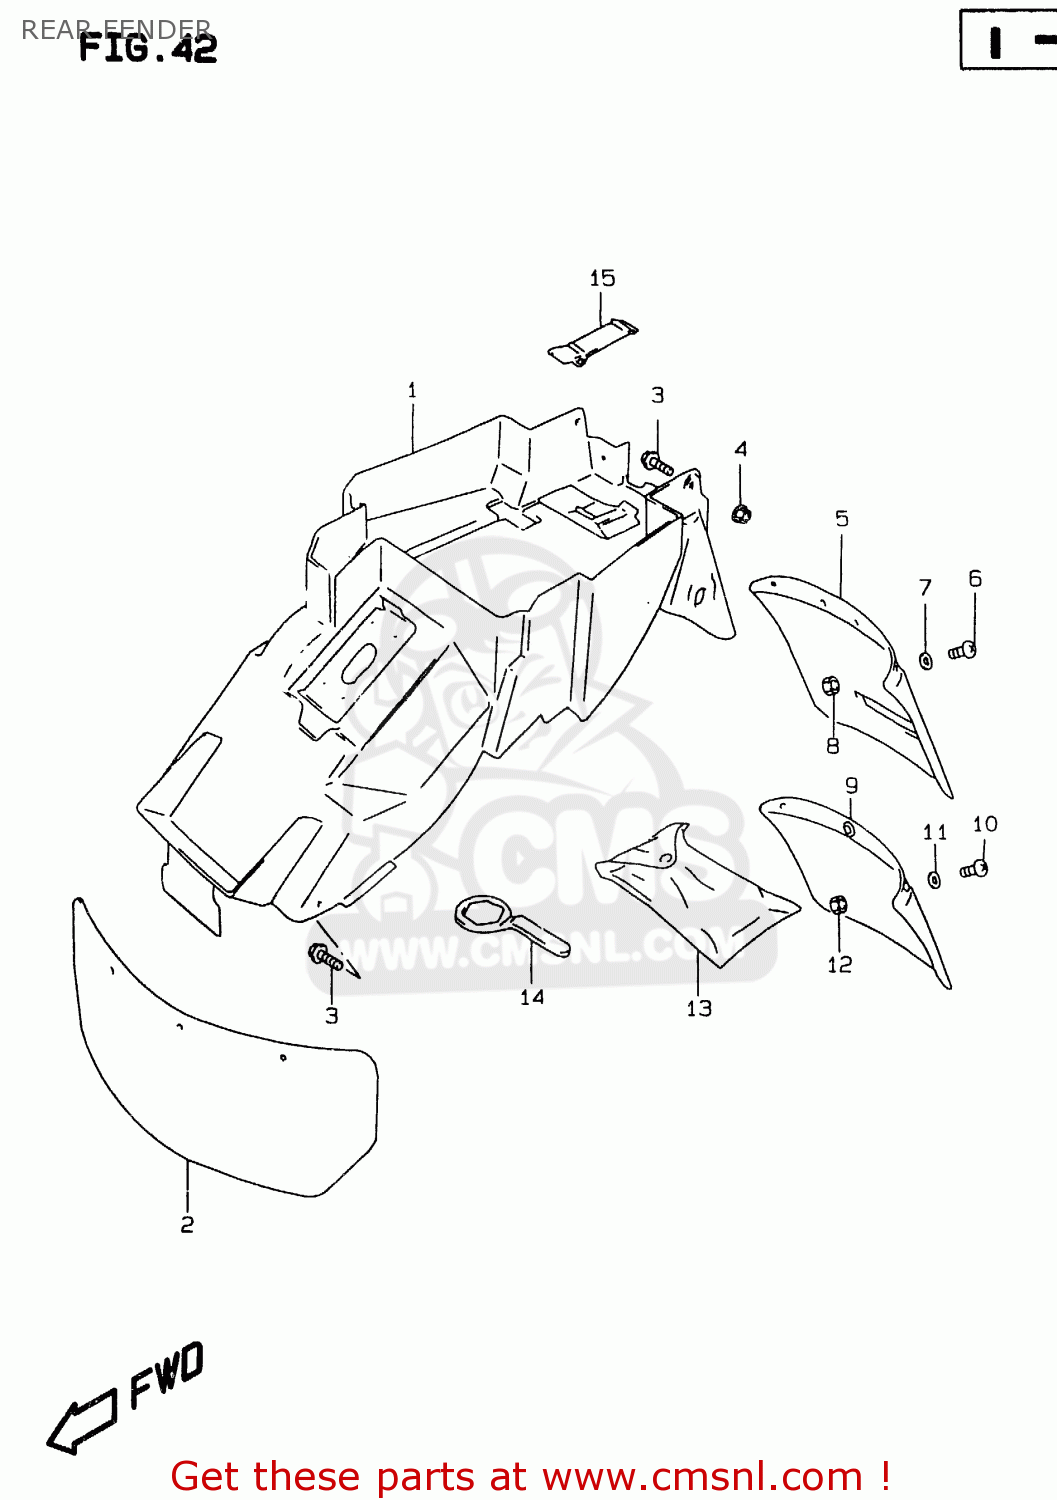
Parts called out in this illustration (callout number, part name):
1	FENDER,RR
2	GUIDE,RR FENDER MUD
3	BOLT(6X16)
4	NUT
5	EXTENSION,RR FENDER
6	SCREW
7	WASHER(6.5X18X1.6)
8	NUT 6MM
9	MUDGUARD,RR FENDER
10	SCREW
11	WASHER
12	NUT 6MM
13	TOOL ASSY
14	RING SPANNER(36)
15	BAND
